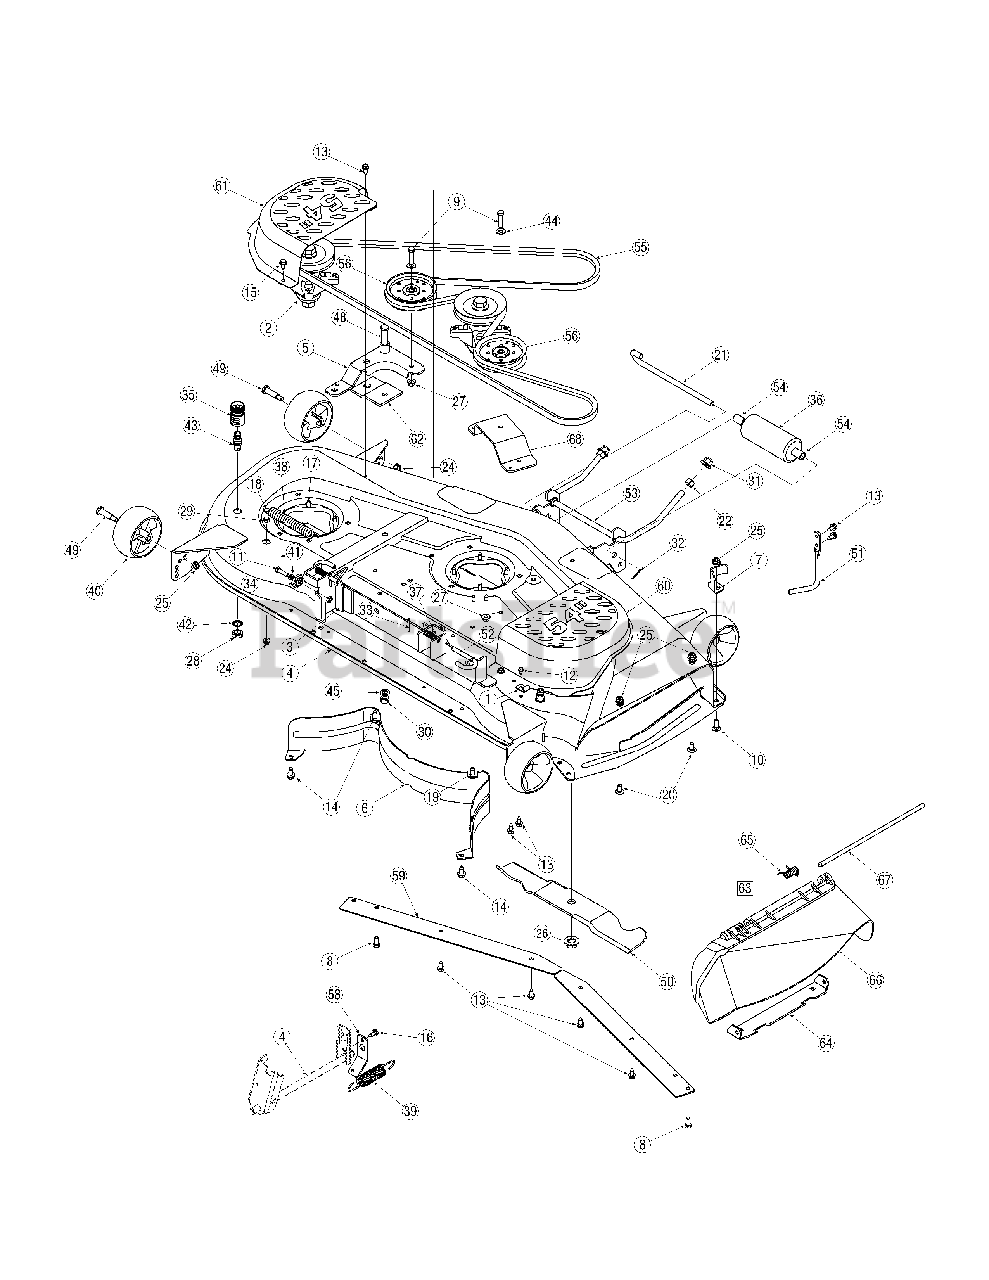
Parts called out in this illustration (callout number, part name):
1	Hook, Retainer Bracket
2	Spindle Assembly
8	Screw, 3/8-16 x.75
9	Screw, 3/8-16 x 1.75
10	Screw, 3/8-16 x 1.0
11	Screw, 5/16-18 x 1.25
12	Screw, 1/4-20 x.500
13	Screw, 5/16-18 x.500
14	Screw, 3/8-16 x.750
15	Screw, 5/16-18 x.875
16	Screw, 5/16-12 x.750
17	Screw, 5/16-18 x.750
18	Screw, 5/16-18 x 2.00
19	Bolt, Carriage, 3/8-16 x 1.00
20	Bolt, Carriage, 3/8-16 x.750
21	Pin, Roller,.5" Dia. x 10.06
22	Nut, Hex, 1/2-13
23	Push Nut, 3/8
24	Nut, Flange Lock, 5/16-18
25	Nut, Flange Lock, 3/8-16
26	Nut, Flange, 5/8-18
27	Nut, Flange Lock, 3/8-16
28	Nut, Hex, M16-1.5
29	Nut, Hex, 5/16-18
30	Nut, Hex Lock, 1/2-13
31	Nut, Hex Lock, 1/2-13
32	Pin, Cotter, 3/32 x 1.00
33	Pin, Cotter, 1/8 x 1.25
34	Deck Adjustment Gear
35	Hose Coupler
36	Front Roller
37	Spring,.531OD x 1.75
38	Spring, Ext.,.850 Dia. x 6.415
39	Spring, Ext., 1.15 Dia. x 5.99
40	Deck Wheel
41	Washer, Lock, 5/16
42	Washer, Lock 5/8 Int. Tooth
43	Port, Water
44	Washer, Flat,.406 x.875 x.059
45	Washer, Lock, 1/2
48	Screw,.625 x 2.50 x 1/2-13
49	Bolt, Shoulder, 3/8-16; 4.96 x 2.50
50	Blade, 18.5"
51	Upstop Rod
52	Rod, Deck Release Handle
53	Rod, Deck Adjust
54	Spacer,.550 ID x.755 OD x 1.1
55	V-Belt
56	Pulley, Idler, 4.25" Dia.
58	Lift Bracket
63	Chute Ass’y, Side Discharge
64	Chute Mounting Bracket
65	Torsion Spring
66	Deflector Chute
67	Hinge Pin
